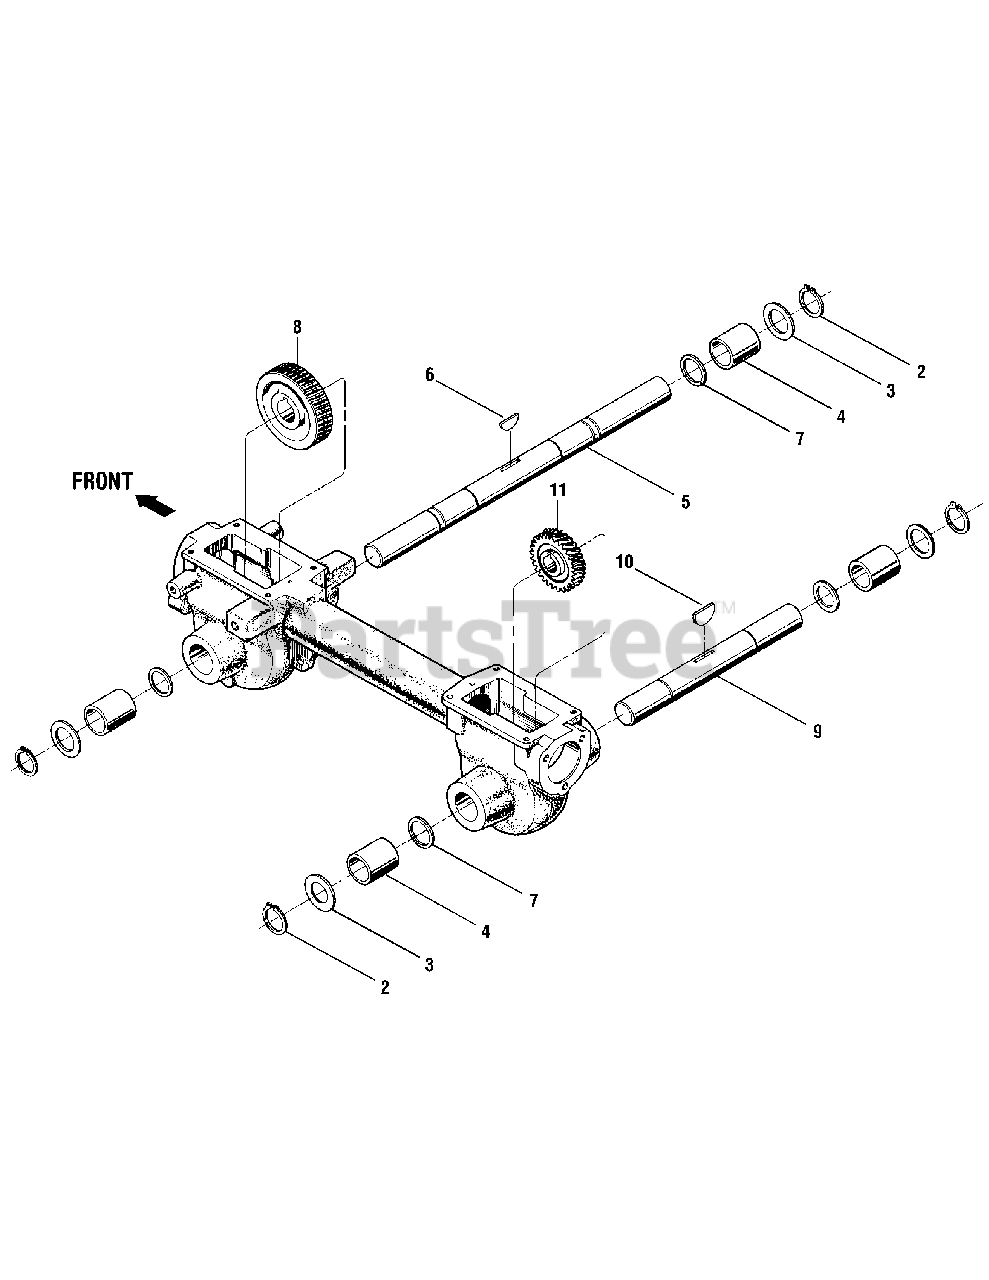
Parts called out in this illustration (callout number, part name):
2	Retainer, Snap Ring
3	Shim, 0.062" thick
3	Shim, 0.030" thick
3	Shim, 0.015" thick
3	Shim, 0.010" thick
3	Shim, 0.005" thick
4	Bronze Bushing
5	Wheel Shaft (model 643C)
5	Wheel Shaft (model 643B)
5	Wheel Shaft (model 645A)
5	Wheel Shaft (model 643D)
6	Key, Hi-Pro, 1/4 x 1
7	Spacer
8	Worm Gear, Wheel Shaft
9	Tiller Shaft
10	Woodruff Key
11	Worm Gear, Tiller Shaft
